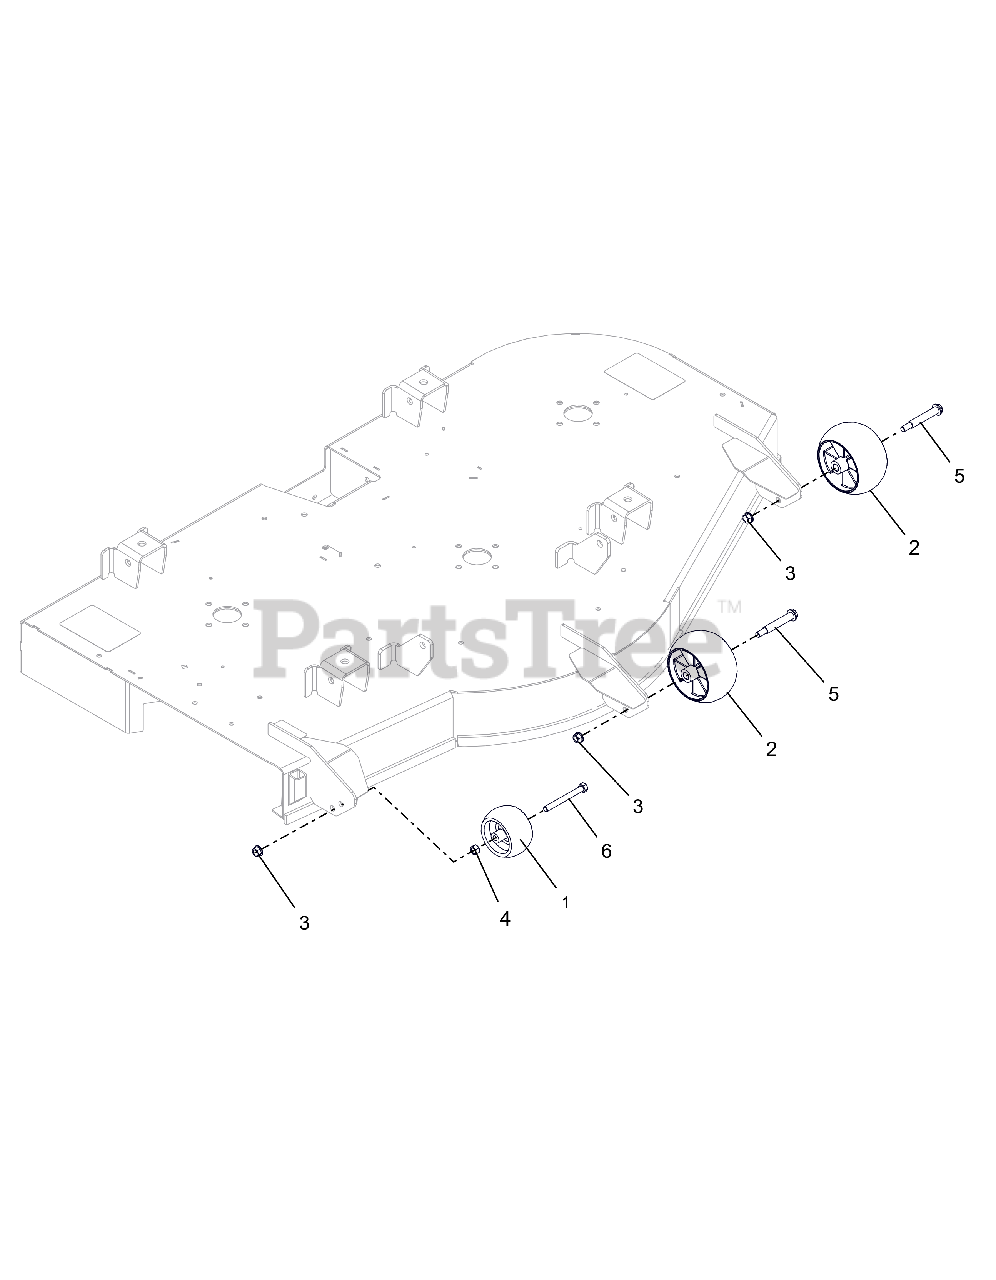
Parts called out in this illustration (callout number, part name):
2	ANTI-SCALP WHEEL - 5X OS
3	NUT-LK-TOP-FLG .38-16 ZC120
4	@NUT-HEX .38-16 YWZC
5	BLT-SHLDR .38-16X2.50 HWH G5
6	BLT, HEX .38-16X3.50 G5 ZCC
